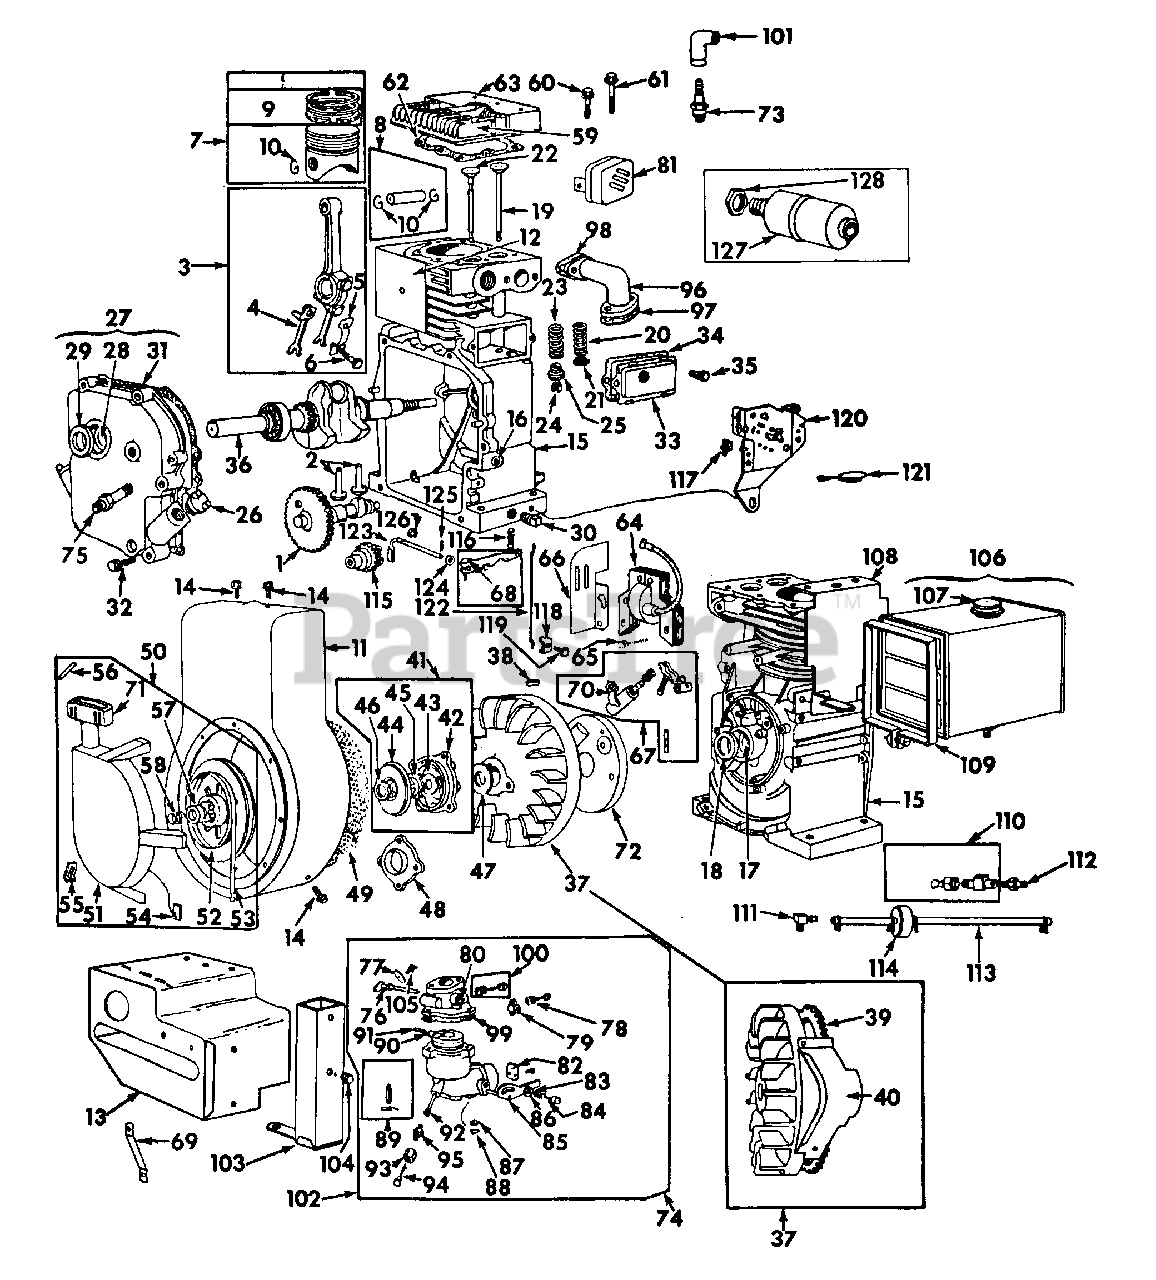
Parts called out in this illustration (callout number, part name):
2	TAPPET, VALVE
3	ROD ASSY, CONNECTING - STANDARD
4	DIPPER, CONNECTING ROD
5	LOCK, SCREW HEAD
6	SCREW, CONNECTING ROD
7	PISTON ASSY, STD
7	PISTON ASSY, .010 O/S
7	PISTON ASSY, .020 O/S
7	PISTON ASSY, .030 O/S
8	PIN ASSY, PISTON - STANDARD
8	PIN ASSY, PISTON - .005 O/S
9	RING SET, PISTON CHROME - STANDARD
9	RING SET, PISTON - STANDARD
9	RING SET, PISTON - .030 O/S
10	LOCK, PISTON PIN
11	HOUSING, BLOWER
12	SHIELD, CYLINDER
13	HOOD, SNOW - W/O OVAL CUT-OUT
13	HOOD, SNOW - W/OVAL CUT-OUT
14	SCREW, 10-32 X 1-1/2 ZND FIL-HD MACH
15	CYLINDER ASSY, ENGINE
16	BUSHING, GOVERNOR SHAFT
17	BUSHING & SEAL
19	VALVE, INTAKE
20	SPRING, INTAKE VALVE
21	RETAINER, INTAKE VALVE
22	VALVE, EXHAUST
23	SPRING, EXHAUST VALVE
24	RETAINER, ROTO-COIL
25	ROTO-COIL, EXHAUST VALVE
26	PLUG, OIL FILLER
27	COVER, CRANKCASE
28	BUSHING & OIL SEAL, COVER
29	SEAL, OIL
30	PLUG, 3/8-18 AUTOMOTIVE SQ-HD OIL DRAIN
31	GASKET, CRANKCASE
32	SCREW, CRANKCASE COVER MOUNTING
33	BREATHER, VALVE CHAMBER
34	GASKET, VALVE COVER
35	SCREW, BREATHER MTG
38	KEY, FLYWHEEL
39	GEAR ASSY, FLYWHEEL RING
40	GUARD, RING GEAR
41	CLUTCH ASSY, REWIND STARTER
42	HOUSING, REWIND STARTER CLUTCH
43	WASHER, THRUST
44	RETAINER, WASHER
45	RATCHET, STARTER
46	SEAL, RATCHET
47	WASHER, SPRING
48	SHIELD, CLUTCH
49	SCREEN, REWIND STARTER
50	STARTER ASSY, REWIND
51	HOUSING, REWIND STARTER
52	PULLEY, REWIND STARTER
53	SPRING, REWIND STARTER
54	BUMPER, REWIND PULLEY
55	SPRING, ANCHOR INSERT
56	PIN, STARTER GRIP PIN
57	ADAPTER, RATCHET SPRING
58	SPRING, RATCHET SPRING
59	HEAD, CYLINDER
60	SCREW, CYLINDER HEAD - SHORT
61	SCREW, CYLINDER HEAD - LONG
62	GASKET, CYLINDER HEAD
63	COVER, CYLINDER HEAD
64	ARMATURE ASSY, MAGNETO
65	SCREW, ARMATURE MOUNTING
67	KIT, IGNITION SERVICE
68	LEVER ASSY, GOVERNOR
69	STRAP, SUPPORT
70	CLAMP, CONDENSER
71	PACKAGE, REWIND STARTER HANDLE & INSERT
72	COVER, BREAKER POINT
73	PLUG, SPARK - CHAMPION
74	CARBURETOR ASSY
75	STUD, STRAP TO CRANKCASE COVER
76	THROTTLE SHAFT & LEVER ASSY
77	VALVE, THROTTLE
78	SPRING, COMPRESSION
79	STOP, COMPRESSION
80	BUSHING, THROTTLE SHAFT
81	MUFFLER, EXHAUST - SQUARE
82	VALVE, CHOKE
83	SPRING, COMPRESSION
84	SCREW, CHOKE LEVER
85	SHAFT & LEVER, CHOKE
86	WASHER, CHOKE LEVER
87	FILTER, DRAIN
88	RETAINER, FILTER
89	VALVE ASSY, FLOAT
90	FLOAT, CARBURETOR
91	PIN, FLOAT HINGE
92	JET ASSY, CARBURETOR
93	NUT, JET NEEDLE PACKING
94	VALVE, NEEDLE
95	RETAINER, NEEDLE VALVE
96	ELBOW, CARBURETOR INTAKE
97	GASKET, INTAKE ELBOW
98	GASKET, CARBURETOR
99	GASKET, CARBURETOR BODY
100	VALVE ASSY, IDLE NEEDLE
101	ELBOW, SPARK PLUG INSULATOR
102	KIT, CARBURETOR OVERHAUL
103	STACK ASSY, CARBURETOR
104	SCREW, 8-32 X 3/8 ZND HEX-HD MACH
105	SCREW, THROTTLE & CHOKE VALVE
106	TANK ASSY, FUEL
107	CAP, FUEL TANK
108	BRACKET, FUEL TANK
109	STRAP ASSY, FUEL TANK
110	OUTLET ASSY, FUEL
111	ELBOW, HOSE CONNECTOR
112	CONNECTOR, FUEL PIPE
113	HOSE. FUEL LINE
114	FILTER, IN-LINE FUEL
115	GEAR, GOVERNOR
116	SPRING, GOVERNOR
117	SWITCH ASSY, STOP
118	CLAMP, CASING
119	SCREW W/LOCKWASHER, HEX-HD
120	BRACKET ASSY, GOVERNOR CONTROL
121	WIRE ASSY, STOP SWITCH - 13 IN. LONG
121	WIRE ASSY, GROUND - 16-3/8 IN. LONG
122	LINK, GOVERNOR
123	CRANK, GOVERNOR
124	WASHER, GOVERNOR CRANK
125	COTTER, GOVERNOR CRANK
126	RETAINER, GOVERNOR CRANK
127	MUFFLER, EXHAUST - ROUND
128	LOCKNUT, MUFFLER
